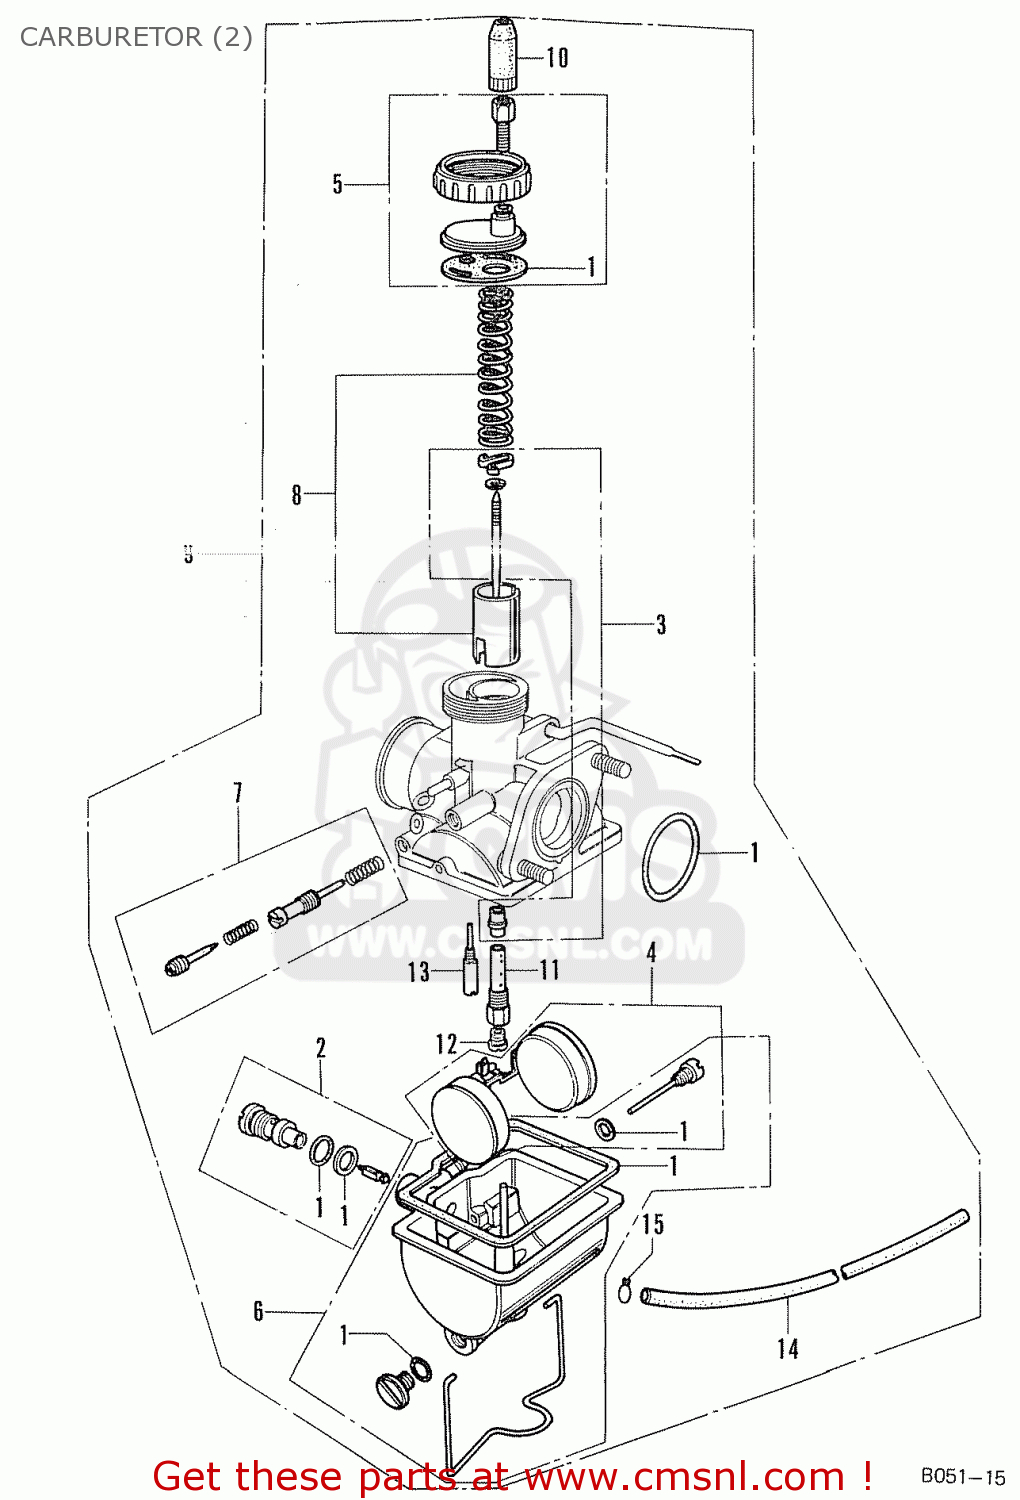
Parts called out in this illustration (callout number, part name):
1	PACKING SET
2	VALVE SET,FLOAT
3	NEEDLE SET,JET
4	FLOAT SET
5	TOP SET
6	CHAMBER SET,FLOAT
7	SCREW SET A
8	VALVE SET,THROT.
9	CARBURETOR ASSY
10	CAP,RUBBER
11	HOLDER,NEEDLE.JET
12	JET,MAIN #80
13	JET,SLOW 40
14	TUBE,FUEL 3.5X300
15	CLIP B7,TUBE
